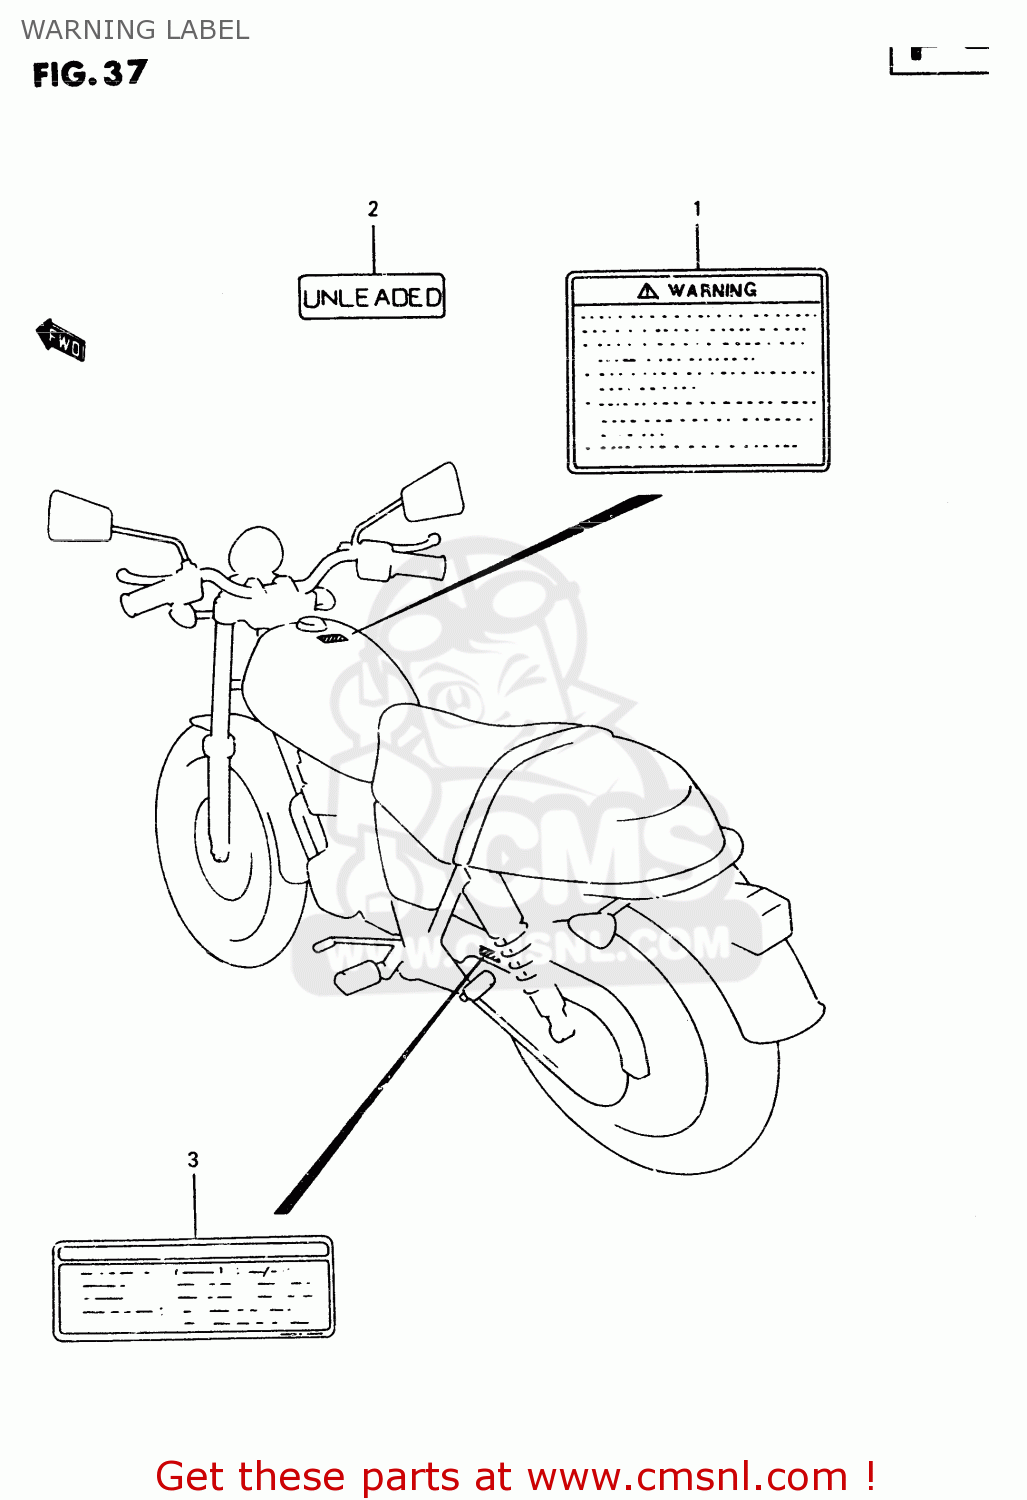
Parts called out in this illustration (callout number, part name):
1	LABEL,WARNING
2	LABEL,CAUTION
3	LABEL, TIRE AIR
4	MANUAL, OWNER'S
